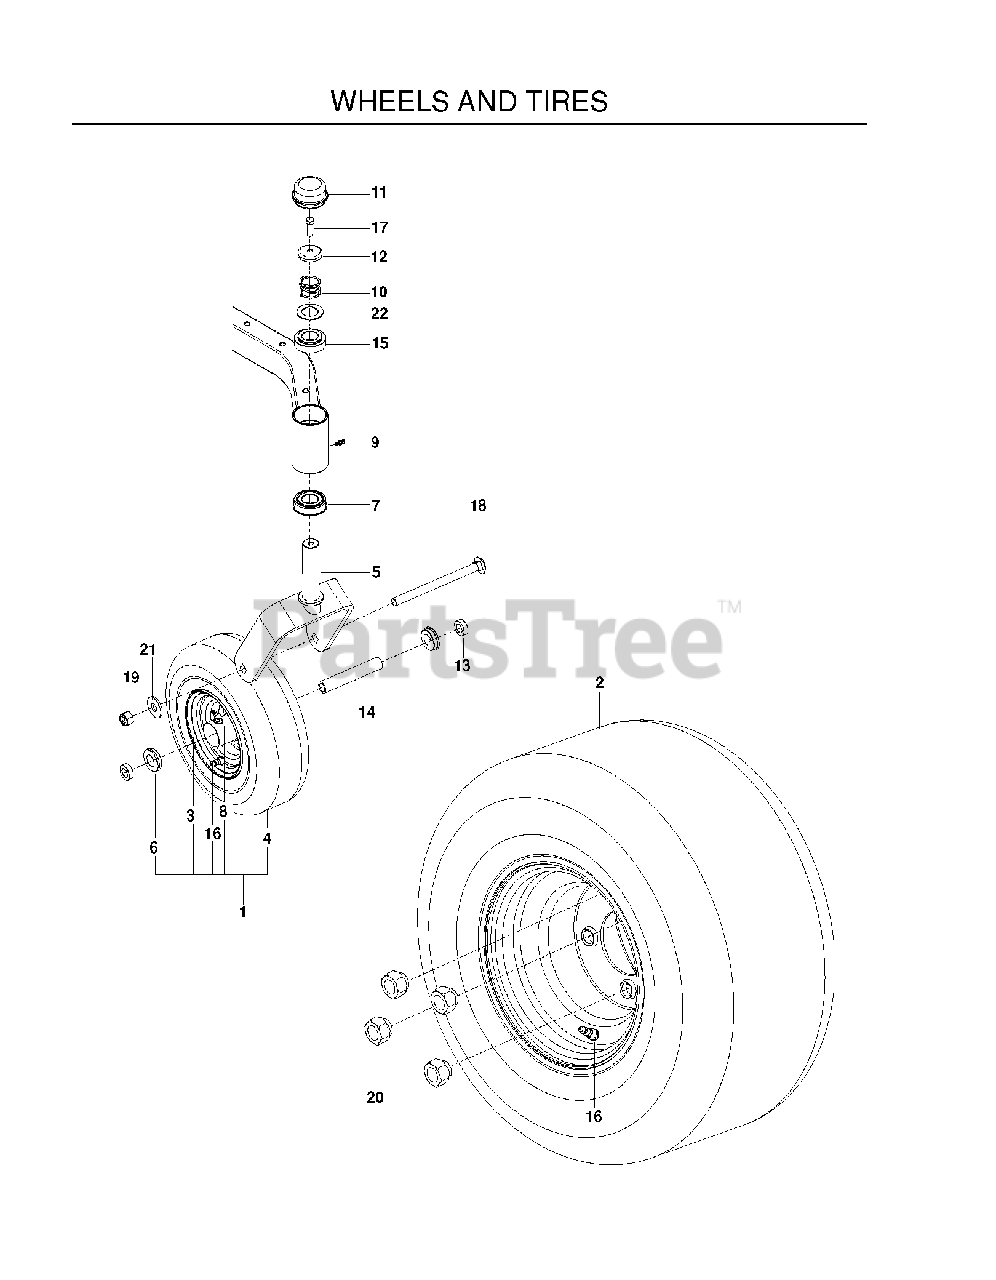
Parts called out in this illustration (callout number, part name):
1	TIRE.ASSEM.CASTER.410-5.BLACK
2	TIRE ASM, 18-8.5 BLK
3	RIM, CASTER TIRE, BLK
4	TIRE.11"X4""-5.4PLY.SMOOTH.KEND
5	YOKE, CASTER, YLW
6	BUSHING, WHEEL, 3/4"
7	BEARING FLANGED
9	ZERK, 3/16, DRIVE IN
10	SPRING, CASTER
11	GREASE CAP
12	CASTER.PLUG
13	SPACER, 5/16"
15	BUSHING, CASTER
16	VALVE STEM TR-412
17	5/16-18X1 HHB G5W/NY
18	RHSNB 1/2-13 X 6.50 GR2 ZD
19	NUT 1/2-13 HEX CNTRLK GR 5 ZD
20	LUG NUT 1/2F
21	WASH USS FLAT 1/2
22	WASHER, 1.025 ID X 1.64
